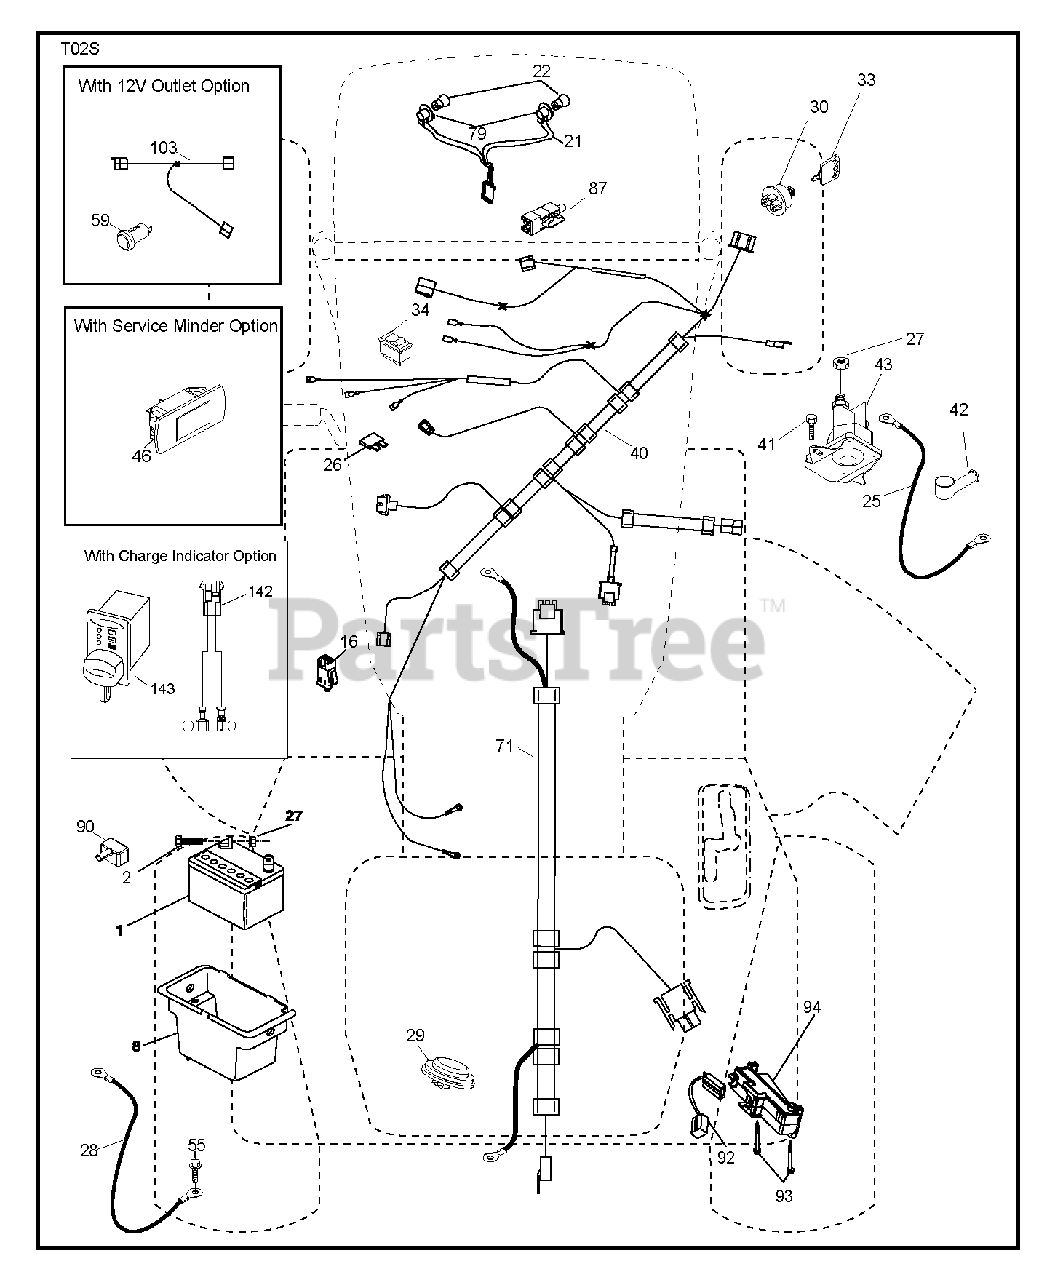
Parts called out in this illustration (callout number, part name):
1	REPL BY 532 12 38-99
8	BOX.BATTERY.MNT.REAR.L
16	SWITCH INTERLOOK PUSH-IN
21	HARNESS.LIGHT W/4152J BULBS
22	LIGHTBULB
25	CABLE.STARTER.8GA.14
26	FUSE 20AMP
27	NUT
29	SWITCH.SEAT.DELTA.OPC.
30	SWITCH.IGN.DELTA.W.LGH.ROS
33	KEY.CHAIN.BLISTER.PACK.GEN.INT
34	SWITCH LT
40	HARNESS IGN. DASH
41	SCREW
42	TERMINAL COVER
43	SOLENOID.W/BRASS.PLUNG
55	SCREW 5/16"
79	BULB HOLDER ASM.
87	SWITCH.INTRLCK.CLUTCH.
90	COVER.TERMINAL.BATTERY
92	HARNESS.PIGTAIL.CONSLE
93	SCREW.PLASTITE
94	MODULE.REVERSE.ROS
